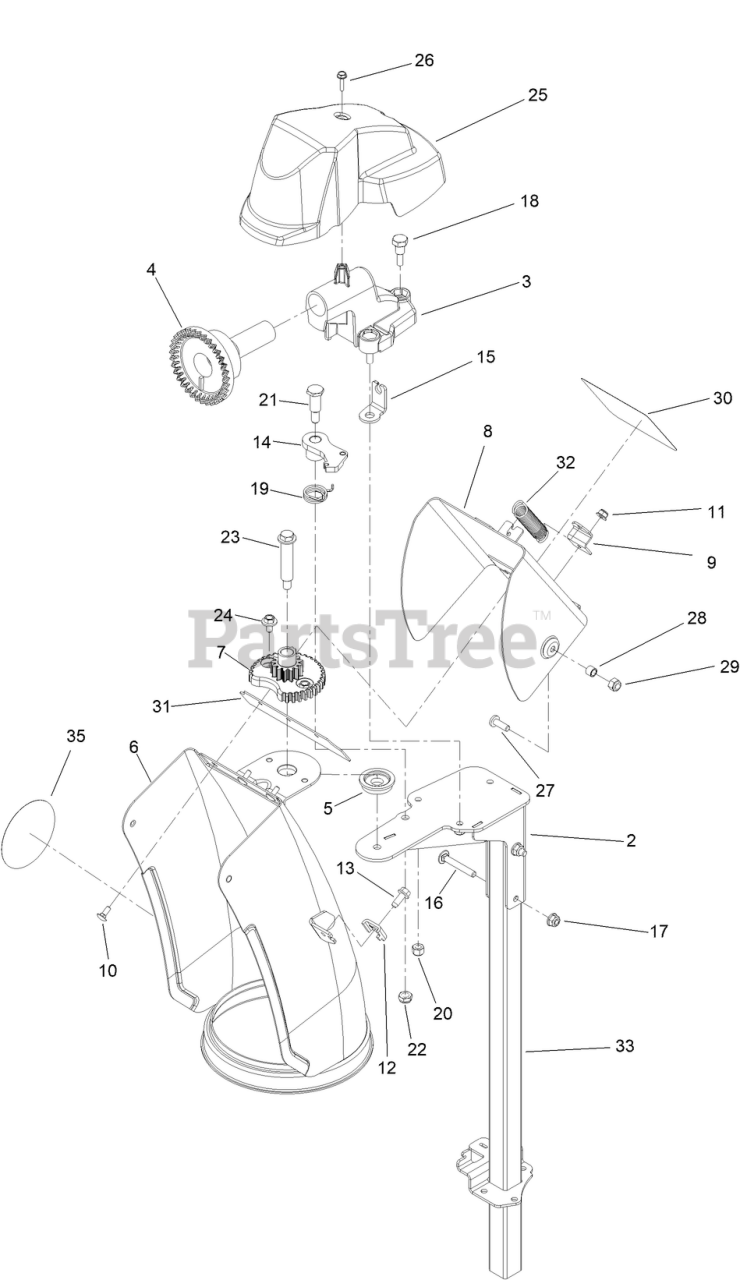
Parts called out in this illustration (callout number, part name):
2	SUPPORT-CHUTE WELD ASM, UPPER
3	MOUNT-GEAR, FACE
4	GEAR-FACE
5	SPACER-CHUTE
6	CHUTE WELD ASM
7	GEAR-CHUTE
8	DEFLECTOR WELD ASM
9	BRACKET-SPRING
10	BOLT-CARR
11	NUT-HF
12	CLAMP-CABLE
13	SCREW-HWH
14	LATCH-CHUTE
15	ANCHOR-CABLE
16	BOLT-CARR
17	NUT-FLANGE, NI
18	SCREW-SHOULDER
19	SPRING-TORSION
20	NUT-HEX
21	SCREW-SHOULDER, HH
22	NUT-HEX
23	BOLT-SHOULDER
24	SCREW-HWH
25	COVER-CHUTE, GEAR
26	SCREW-HWH
27	SCREW-PH
28	SPACER
29	NUT-HEX
30	DECAL-DANGER
31	GASKET-DEFLECTOR
32	SPRING-CHUTE, UPPER
33	CHUTE SUPPORT ASM [BLACK]
35	DECAL - ANTI-CLOG
